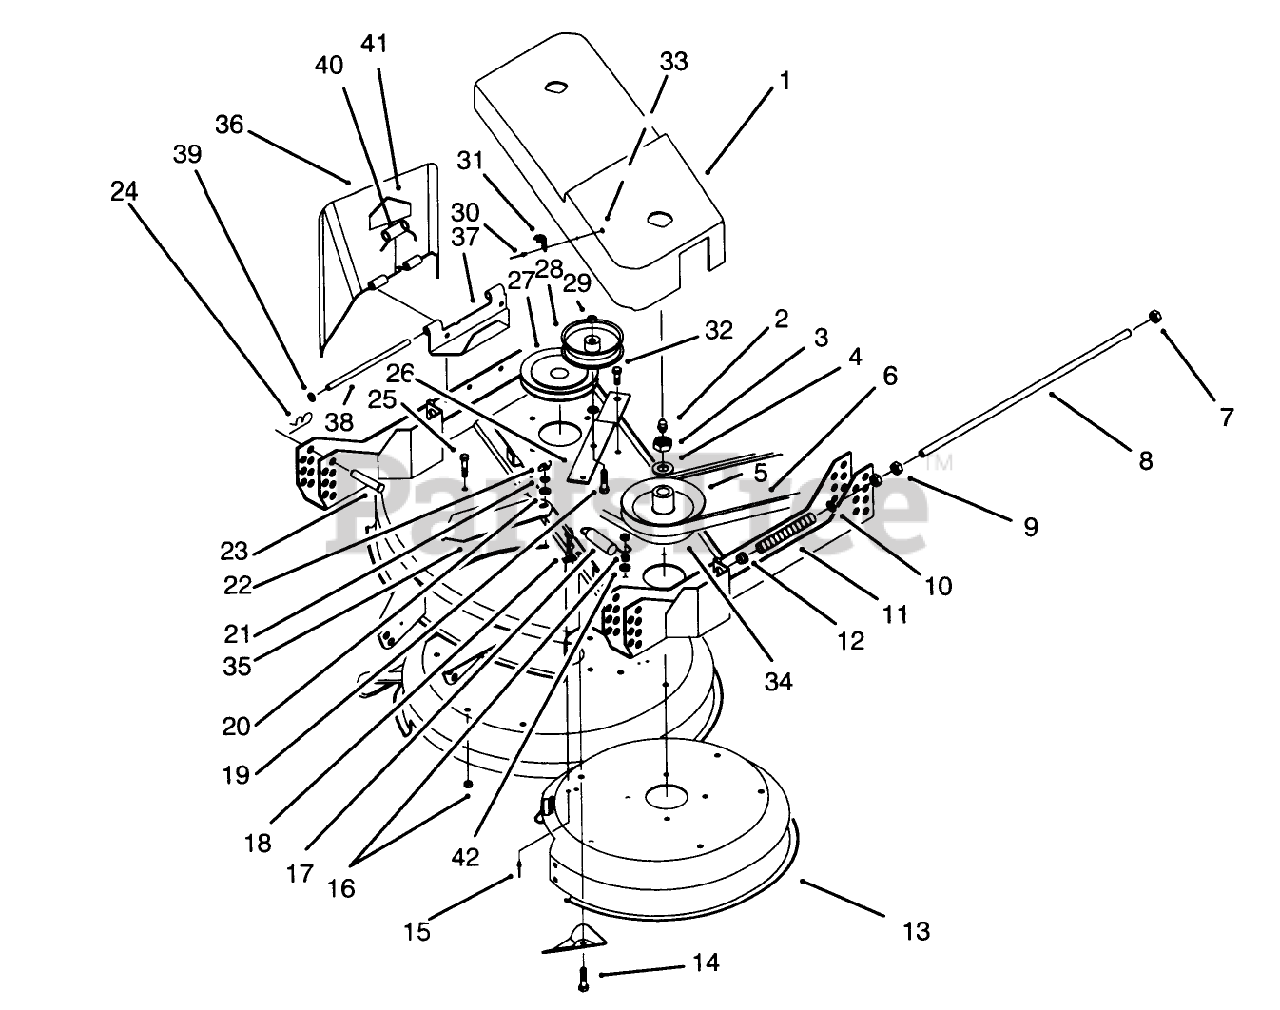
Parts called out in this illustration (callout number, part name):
1	COVER-PULLEY
2	FITTING-GREASE
3	NUT-HEX
4	WASHER
5	PULLEY-CENTER
6	V-BELT, DECK DRIVE
7	NUT-LOCK, NI
8	SHAFT-ADJUSTING
9	NUT-JAM
10	WASHER
11	SPRING
12	BUSHING-FLANGE
13	Deck (Incl. Ref. #1 & 10 on pg.1)
14	SCREW-HH
15	NUT-LOCK, NI
16	NUT-LOCK, NI
17	SPRING-EXTENSION, DECK
18	HANDLE ASM
19	SCREW-HH
20	WASHER-FLAT
21	WASHER-LOCK
22	NUT-WING
23	PIN-CLEVIS
24	PIN-HAIR
25	SCREW-HH
26	Lever-Idler
27	PULLEY-OUTSIDE
28	PULLEY-IDLER
29	NUT-LOCK, NI
31	KEEPER-LATCH
32	SCREW-SHOULDER
33	WASHER-BACK
34	V-BELT, DECK
35	Cover-Slot
36	Deflector-Discharge
37	Hinge-Deflector
38	PIN-HINGE
39	RING-RETAINING, EXTERNAL
40	SPRING
41	DECAL-DANGER
42	WASHER-PLAIN
